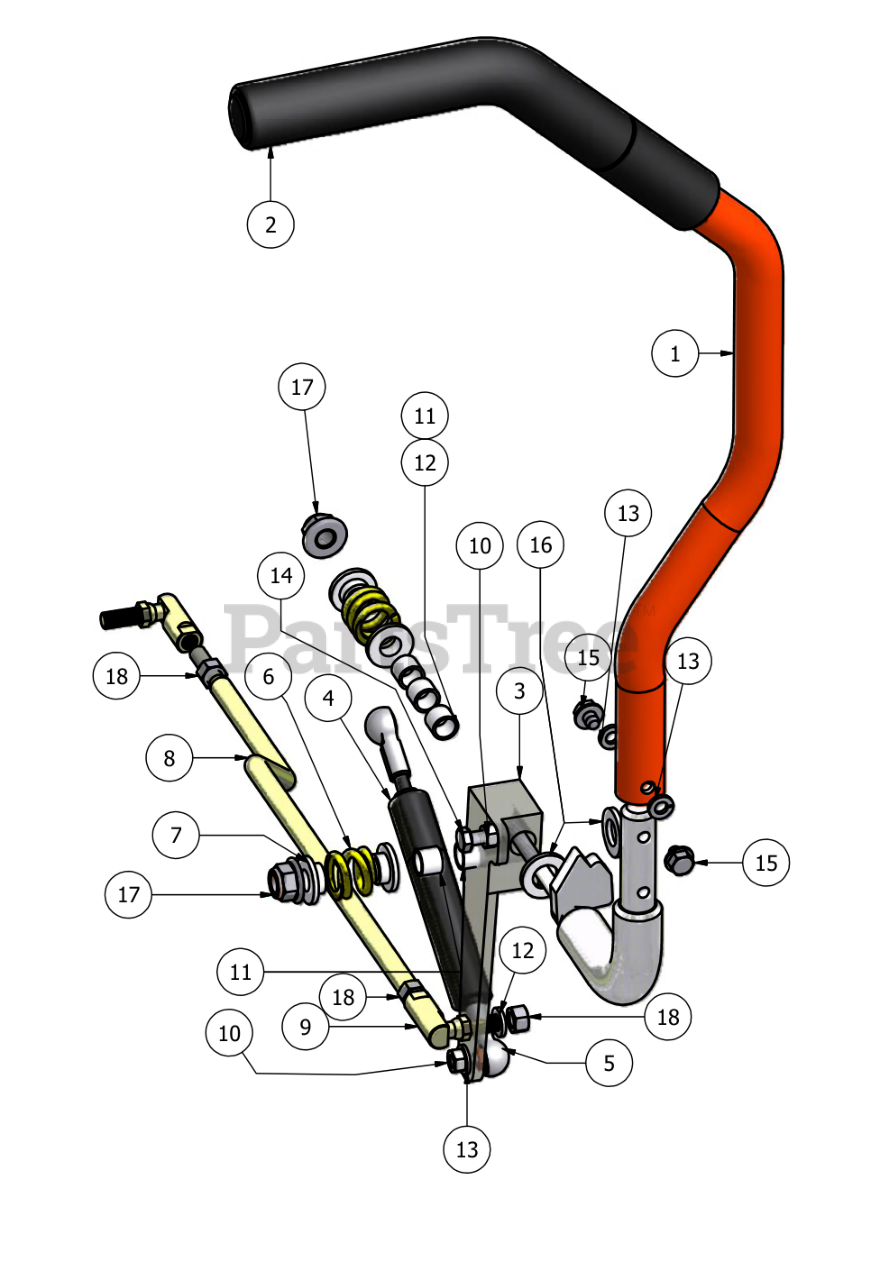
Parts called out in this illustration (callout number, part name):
1	Right Drive Arm
1	Left Drive Arm
2	Rubber Steering Handle
3	Left Drive Arm Lever
3	Right Drive Arm Lever
5	10mm Damper Ball Stud
6	Drive Lever Spring
7	.515 ID Nylon Shoulder Washer
9	3/8-24 Ball Joint
11	.507 ID Nylon Bushing
12	3/8" Lock Washer
13	5/16" Lock Washer
14	5/16"x3/4" Hex Bolt
15	5/16"x1/2" Flange Bolt
16	.505 ID Plastic Washer
17	1/2" Flange Lock Nut
18	3/8" Fine Thread Nut
